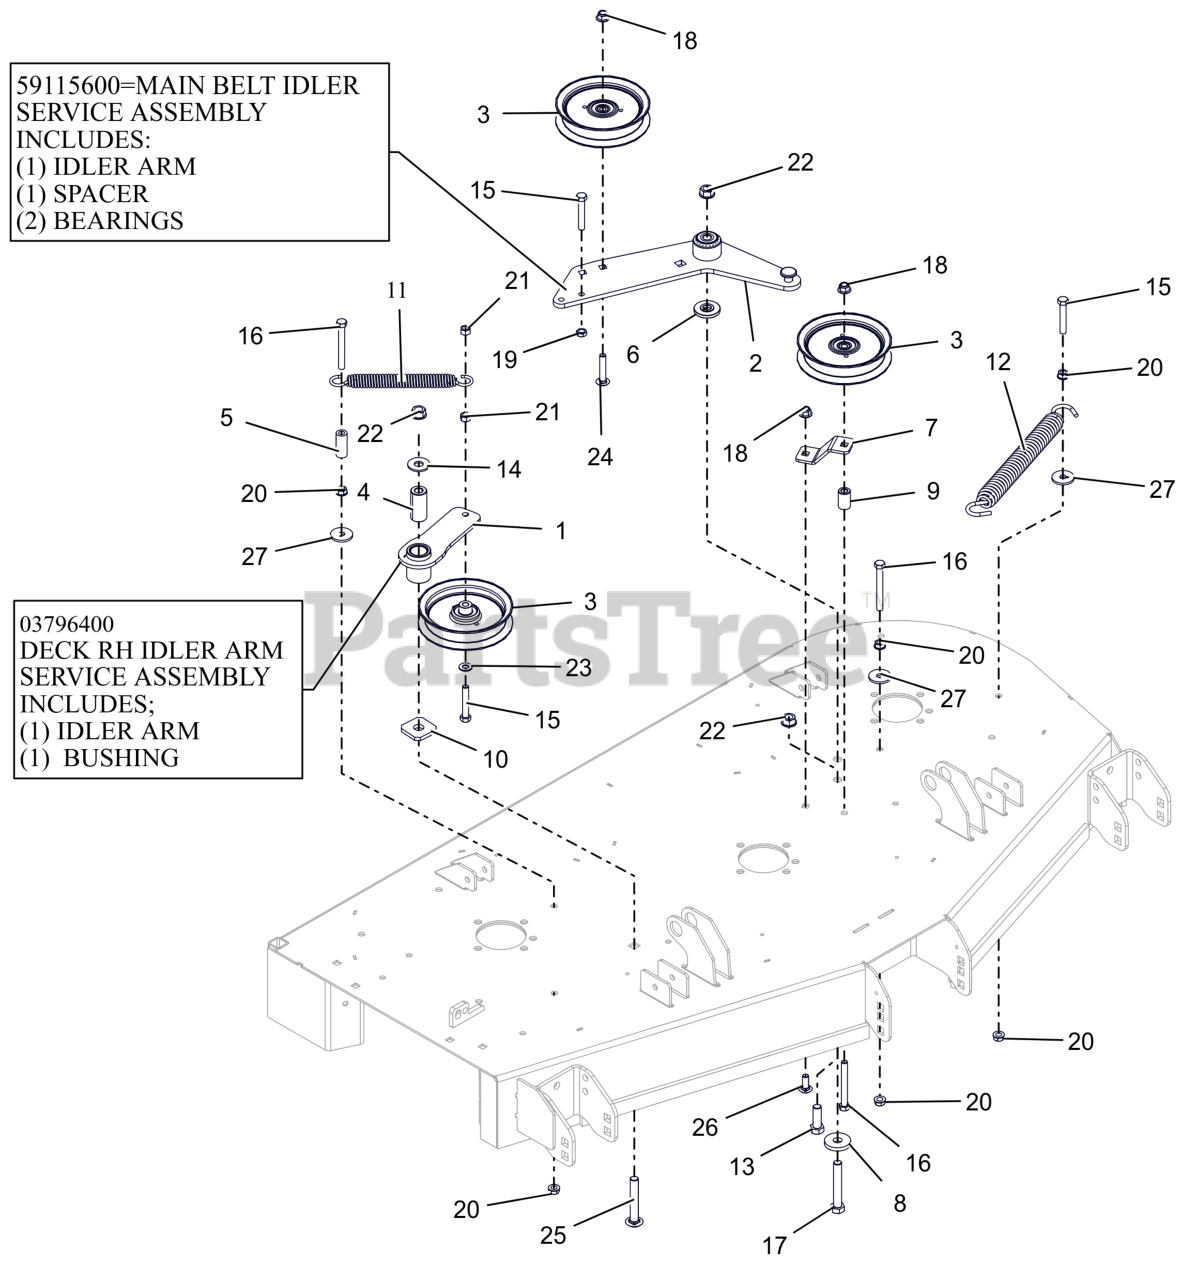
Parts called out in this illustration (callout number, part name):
1	WMT, IDLER ARM - BLACK
2	WLDMT, DECK PTO IDLR ARM
3	IDLER, FLAT 5.00"
4	BSHG, SPCR .502X.997X2.03 PM
5	HOSE, .38 X 1.65
6	SPACER, IDLER ARM
7	PTO FIXED IDLER MTG BRKT-ORG
8	WSHR-FL-STL 0.557X1.625X0.25 ZCC
9	BUSHING, SLV .380X.750X1.190
10	WSHR-FLT .640X1.75X.250
11	SPRING, EXTENSION
12	SPRING, EXTENSION
13	BLT,HEX .50-13X1.50 G5 ZCC
14	WSHR,FLT .563X1.375X.109 ZCC
15	BLT,HEX .38-16X2.25 G5 ZCC
16	BLT, HEX .38-16X3.25 G5 ZCC
17	BLT,HEX .50-13X3.25 G5 ZCC
18	NUT,NYL-FLG .38-16 GF ZCC
19	NUT-JAM .375-16 G2 ZCC
20	NUT, SPNLK-FLG .38-16 G5 ZCC
21	NUT-LK-CTR .38-16 ZC120
22	NUT-LK-CTR-FLG .500-13 GG ZCC
23	WSHR,FLT .406X.812X.065 ZCC
24	BLT,RHSSN.375-16X2.00 G5 ZCC
25	BTL,RHSSN .500-13 X 3.25 G5 ZCC
26	BLT,RHSSN .38-16X1.00 G5 ZCC
27	WSHR,FLT .406X1.375X.135 ZCC
